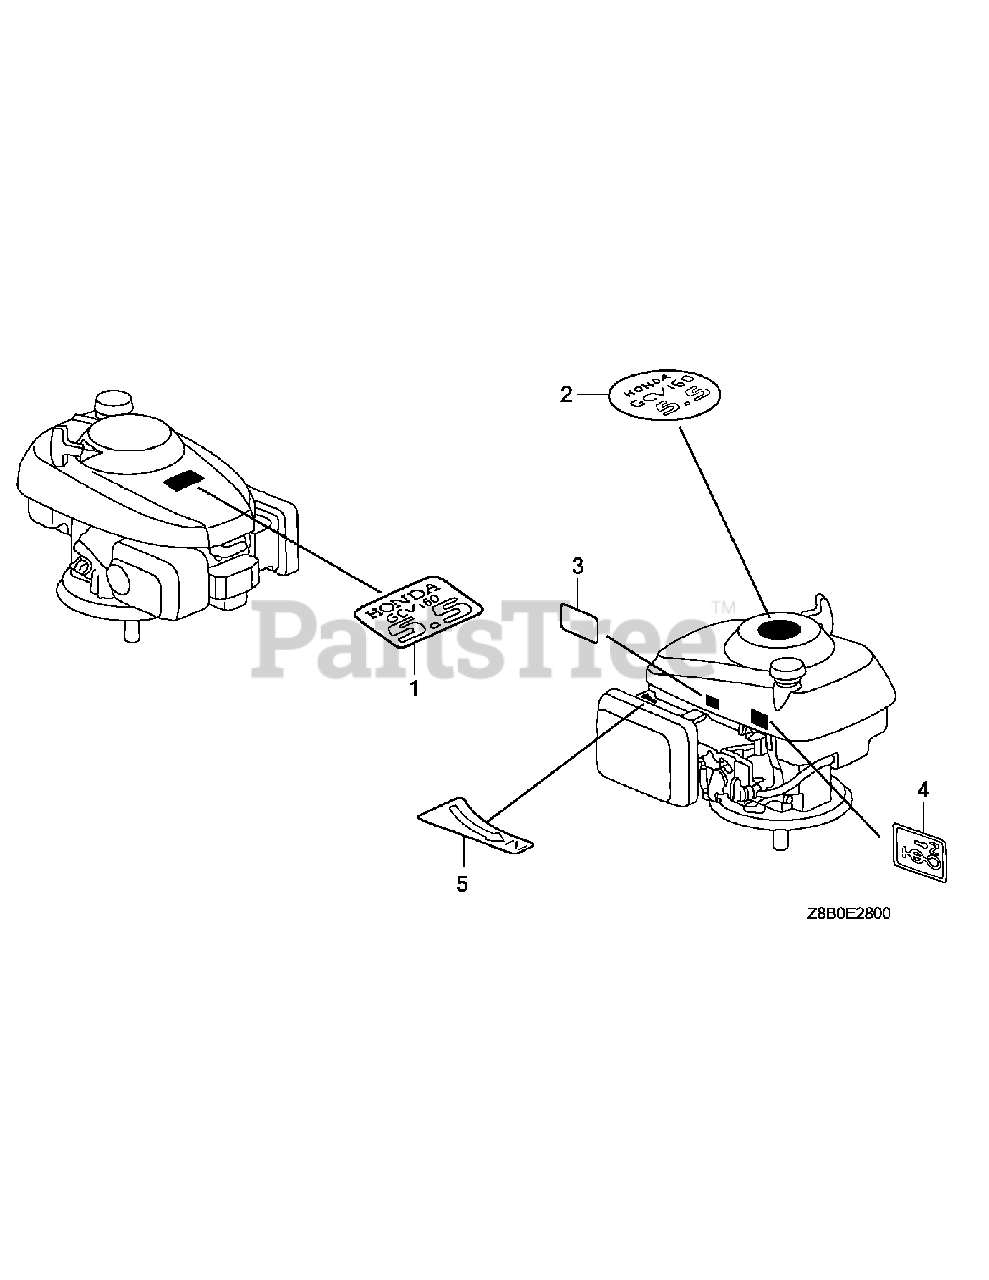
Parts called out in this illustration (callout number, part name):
1	MARK, EMBLEM (GCV160 5.5)
2	MARK, EMBLEM (GCV160)
3	LABEL, WARNING
4	MARK, CHOKE
5	MARK, CHOKE INDICATION
